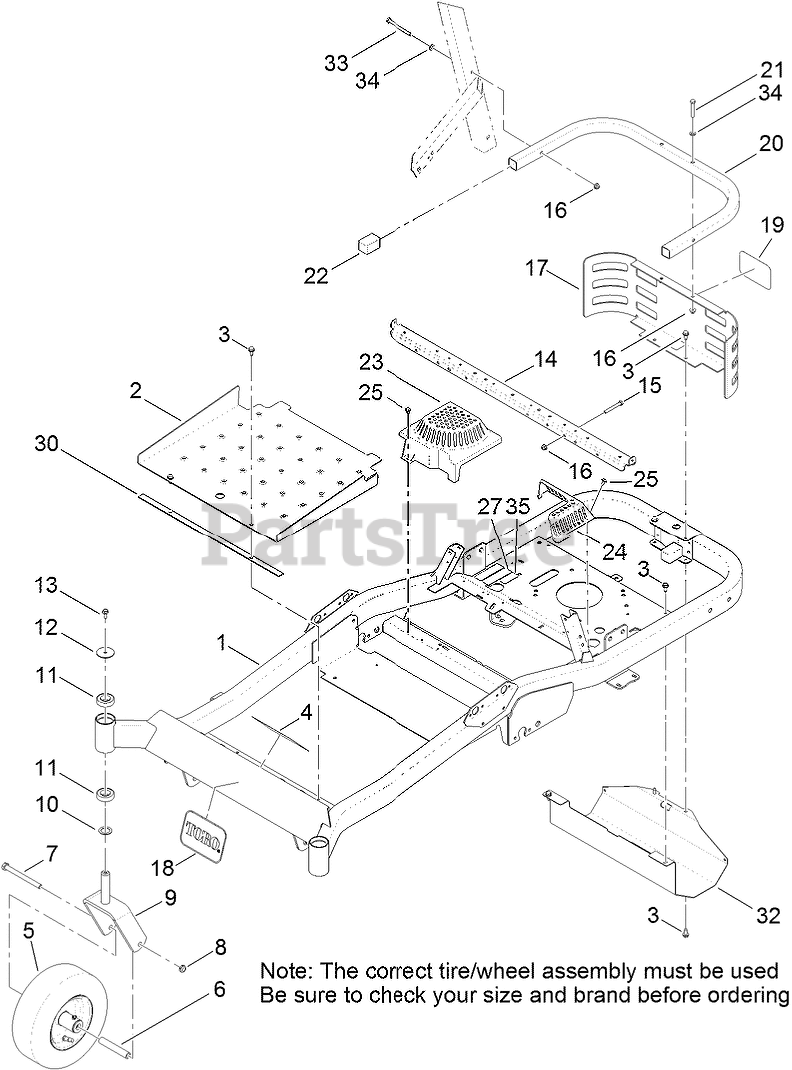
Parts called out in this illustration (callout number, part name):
2	PAN-FLOOR
3	SCREW-HWHTF
4	DECAL-SAFETY
5	TIRE and Wheel ASM (Kenda)
5	TIRE AND WHEEL ASM (C S T)
6	BUSHING-SPANNER
7	SCREW-HH
8	NUT-LOCK, NI
9	CASTER FORK ASM
10	WASHER-THRUST
11	BEARING-BALL
12	WASHER
13	SCREW-HHF
14	SUPPORT-SEAT
15	SCREW-HH
16	NUT-HF, NI
17	GUARD-REAR
18	DECAL
20	TUBE-GUARD
21	SCREW-HH
23	COVER-FAN, RH
24	COVER-FAN, LH
25	SCREW-HHFTF
27	DECAL-EMISSIONS, E P A
30	STRIP-VIBRATION, ANTI
32	GUARD-MUFFLER
33	SCREW-HH
34	WASHER-PLAIN
35	DECAL-LOCATION, SERVICE DEALER
